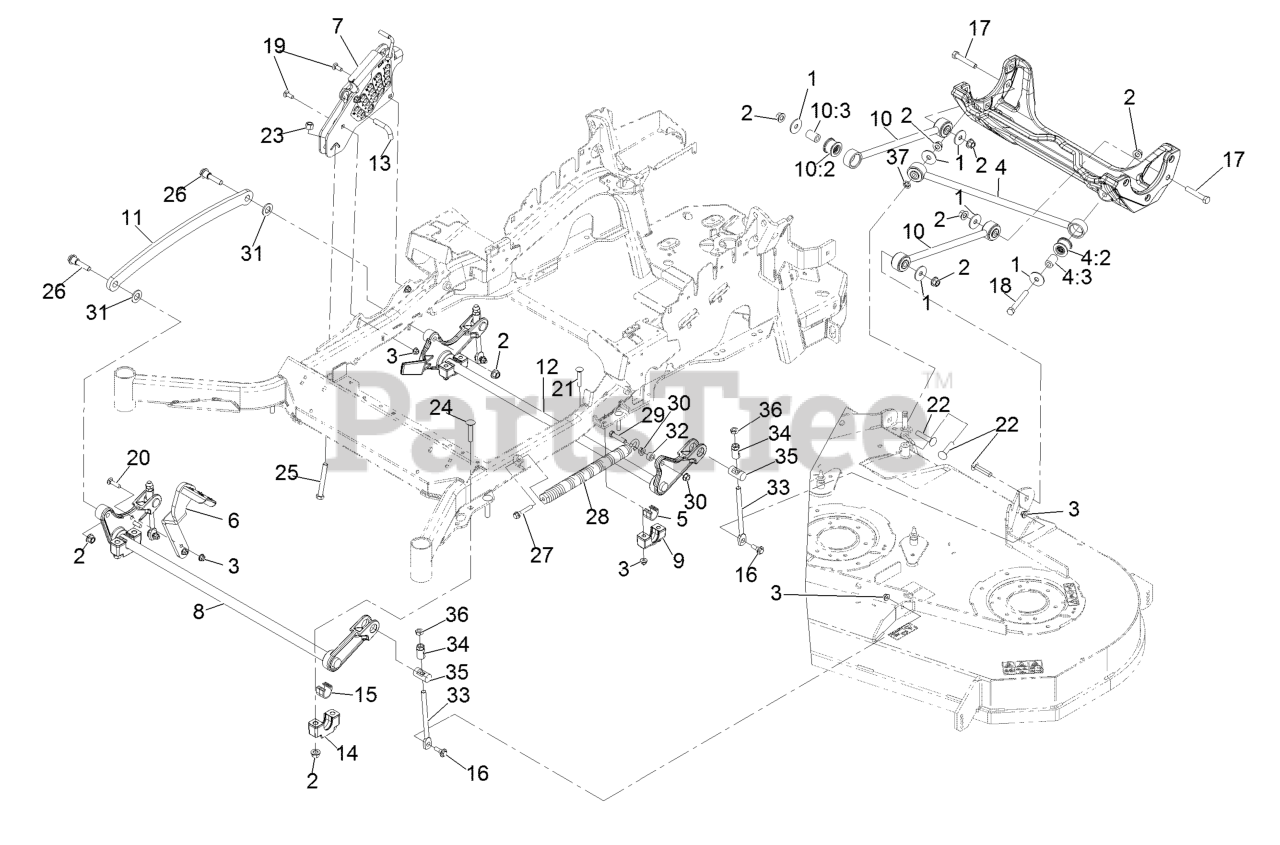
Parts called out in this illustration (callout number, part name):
2	Nut-Lock 1/2-13
3	Nut-Nyloc 3/8-16 Flg
4	Panhard Rod ASM
4:2	Bushing-Suspension, Rubber
5	Bearing-Cross Shaft, Rear
6	Lever-Foot
7	HOC ASM
8	Decklift-Front
9	Support-Cross Shaft, Bearing Rear
10	Deck Strut ASM
10:2	Bushing-Suspension, Rubber
11	Link-Lift, Deck
12	Lift-Deck, Rear
13	Pin-HOC
14	Support-Cross Shaft, Bearing
15	Bearing-Cross Shaft, Front
16	Screw-Hex Flange 3/8-16 X .80
17	Screw-HH 1/2-13 X 3
18	Screw-HH 1/2-13 X 4
19	Bolt-Carriage 3/8-16 X 1
20	Bolt-Carriage 3/8-16 X 1 1/2
21	Bolt-Carriage 3/8-16 X 2 1/4
22	Bolt-Carriage 1/2-13 X 2 1/2
23	Nut-Nyloc 1/2-13
24	Bolt-Carriage 1/2-13 X 2 1/2 Spl Neck
25	Bolt-HH 1/2-13 X 4 Tap
26	Screw-Hex Flange 1/2-13 X 1.90
27	Screw-Shcs 3/8-16 X 2.212
28	Spring-Extension
29	Screw-HH 7/16-14 X 2
30	Nut-Whizlock 7/16-14
31	Washer-3/4 SAE
33	Link-Adjuster, Deck Lift
34	Adjuster-Lift, Deck
35	Trunnion
36	Nut-Jam 1/2-13
37	Nut-Push
